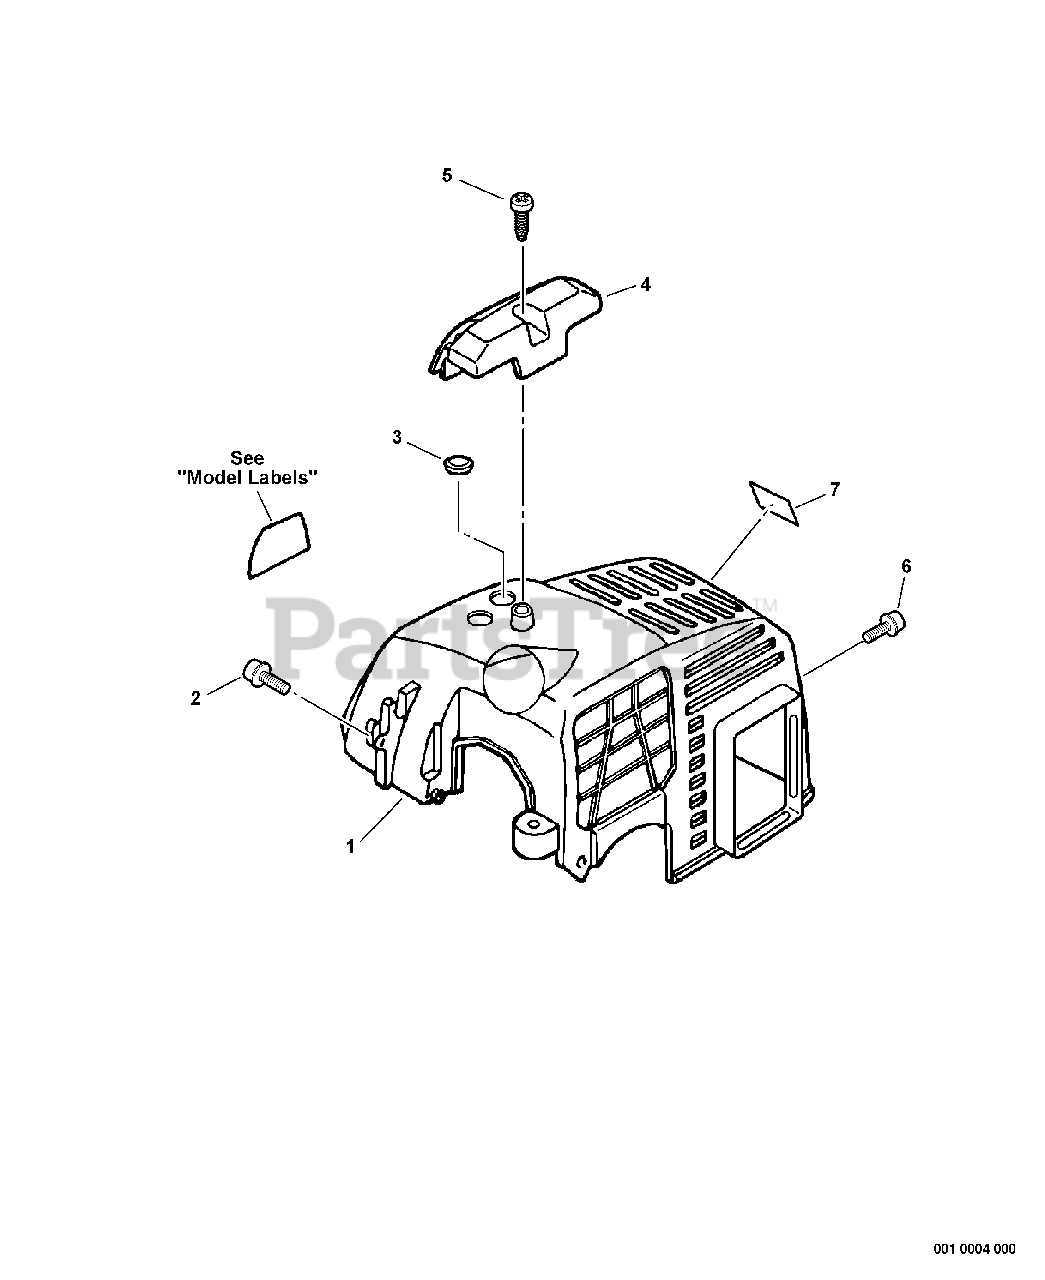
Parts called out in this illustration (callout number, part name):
1	COVER, ENGINE
2	SCREW - 4X12 -- TAPPING
4	GUARD - TOP
5	SCREW - 5X16 -- TAPPING
6	SCREW - 4X8
7	LABEL - HOT SURFACE
